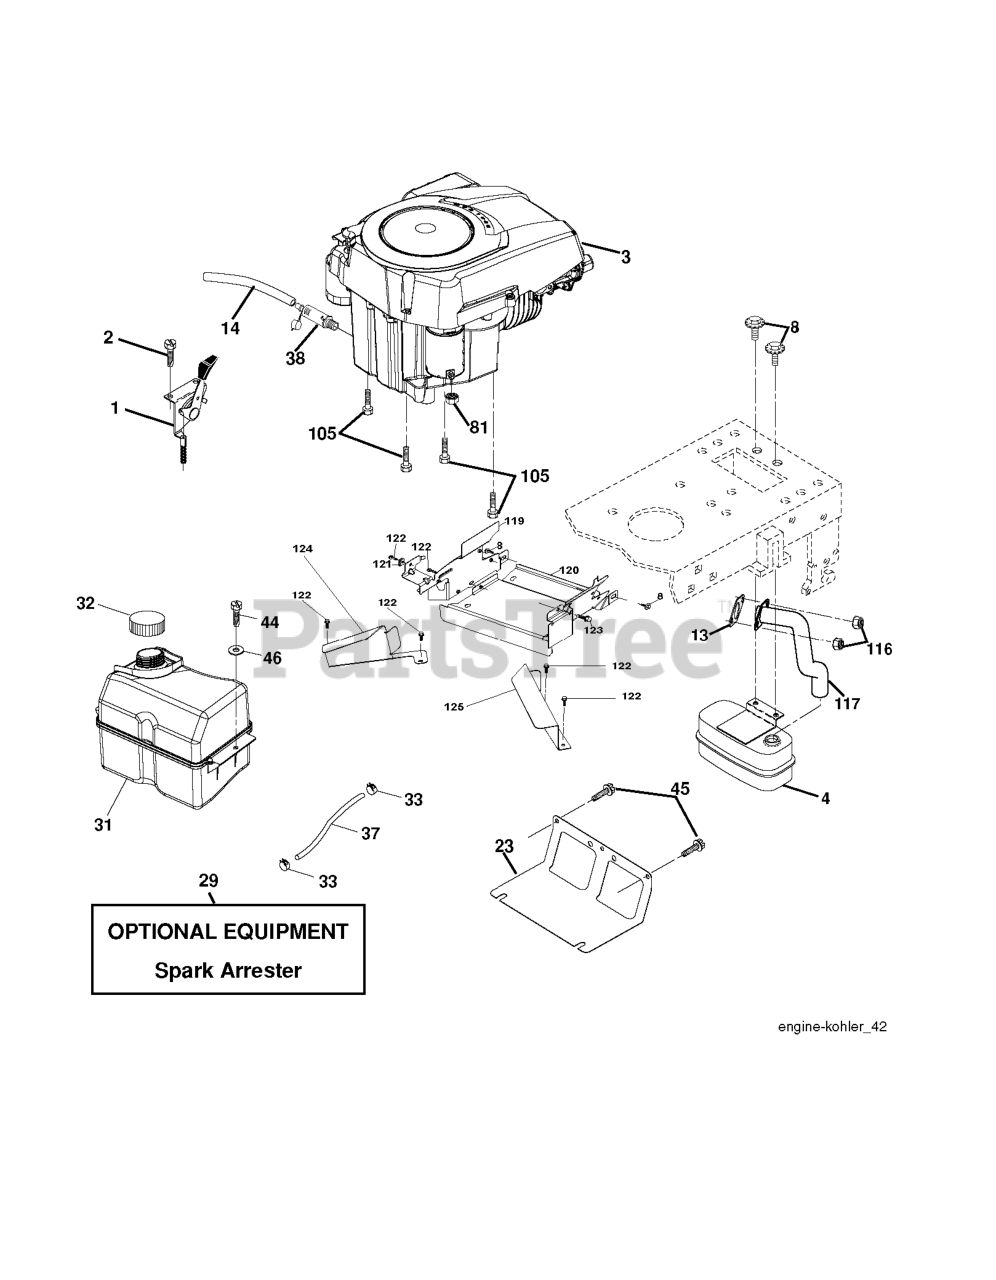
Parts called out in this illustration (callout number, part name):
1	CONTROL.TH/CK.C.
2	SCREW
4	MUFFLER.SINGLE.CYL.KOHL/B&S
8	BOLT.5/16-18UNCX3/4 W/SEMS.BLK
13	GASKET.EXHAUST.KOHLER
14	TUBE, DRAIN OIL ASM.
23	SHIELD.BROWNING.DBR.GUARD
29	KIT.SPARK ARRESTOR 794945 B&S
31	RP TANK FUEL FRT 1.5 GAL
32	FUEL CAP
33	HOSE CLAMP
37	LINE.FUEL.20
38	PLUG DRAIN OIL EASY
44	SCREW HEXWSHR 1/4-20X3/4
45	SCREW, 3/8-16X3/4
81	NUT
105	SCREW 3/8-16X1
116	NUT.HEX.FLANGE.TOPLOCK
117	RP.TUBE.EXHAUST.KOHL.COURAGE
119	LENKRAD
120	GUARD 532199767
122	SCREW.1/4-20X5/8
123	SCREW, 5/16-18 X 1/2
